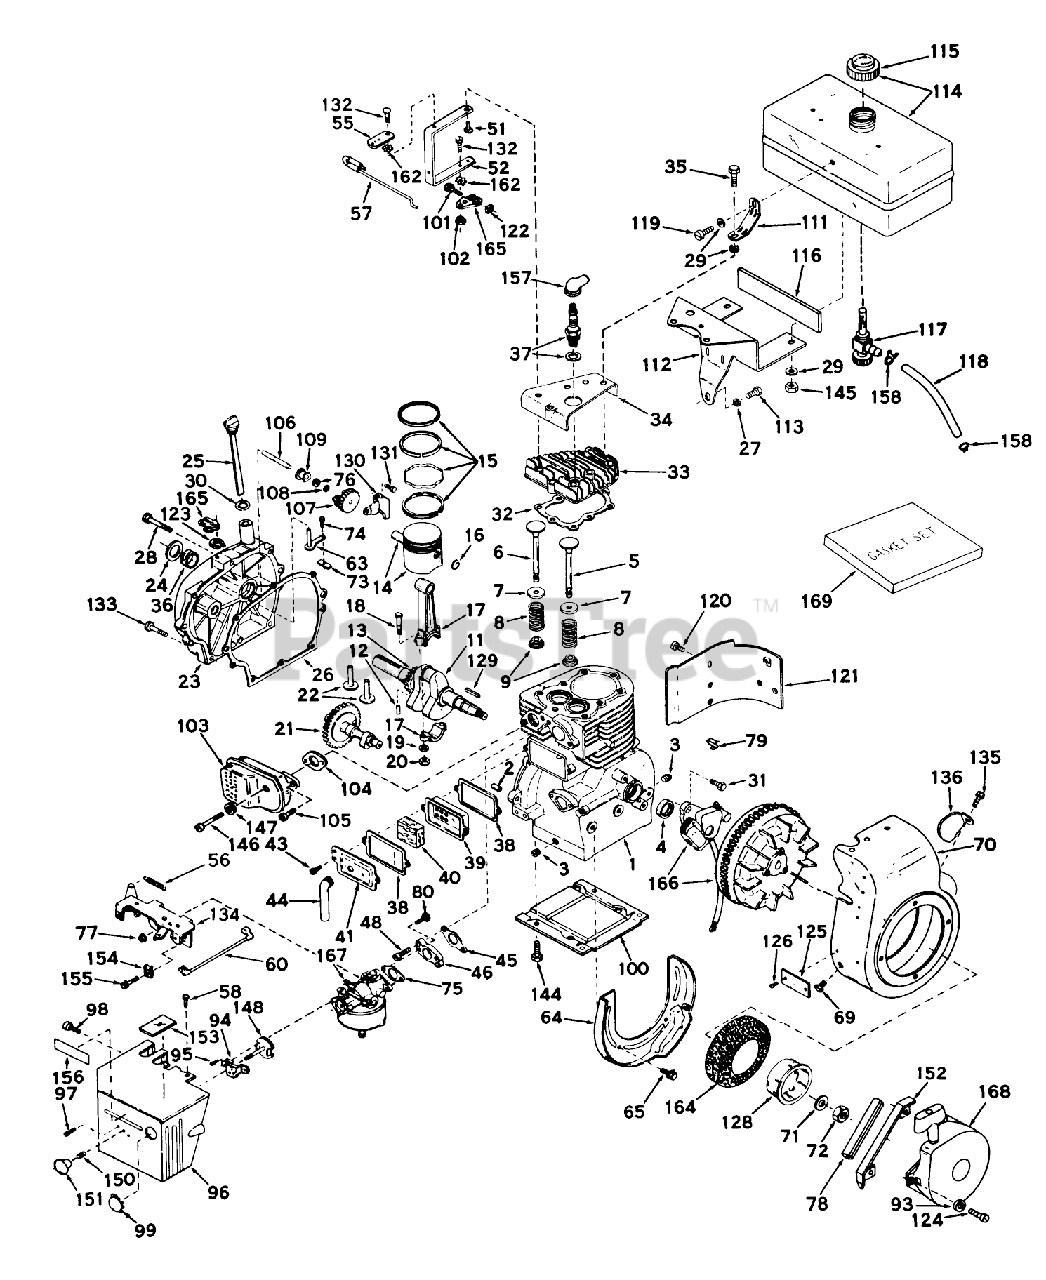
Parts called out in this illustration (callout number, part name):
1	Cylinder Assy. (Incl. Nos. 2, 3 4)
2	Pin-Dowel
3	Plug-Drain, Oil (SQH 1/4-18)
4	Seal, Oil
5	Valve, Intake (Std.)(Incl. No. 9)
5	Valve, Intake (1 /32" oversize)(Incl. No. 9)
6	Valve, Exhaust (Standard)(Incl. No. 9)
6	Valve, Exhaust (1/32" oversize)(Incl. No. 9)
7	Cap-Spring, Valve
8	Spring-Valve
9	Keeper-Spring, Valve
11	Crankshaft Assy. (Incl. Nos. 12 13)
12	Pin, Groove
13	Gear-Crankshaft
14	Piston Pin Assy., Std., (Incl. 2 of No. 16)
14	Piston Pin Assy., .010 oversize (Incl. 2 of No. 16)
14	Piston Pin Assy., .020 oversize (Incl. 2 of No. 16)
15	Ring Set (Standard)
15	Ring Set (.010 Oversize)
15	Ring Set (.020 Oversize)
17	Rod As sy. (Incl. Nos. 18, 19 20)
18	Bolt, Connecting Rod
19	Washer
21	Camshaft
22	Lifter Valve
23	Cover, Cylinder (Incl. Nos. 24 106)
24	Oil Seal
25	Dipstick, Oil (Incl. No. 30)
26	Gasket-Cover, Cylinder
27	Lockwasher
28	Screw (1/4-20 x 1-1/4)
29	Washer
30	Gasket
31	Screw
32	Gasket-Head, Cylinder
33	CYLINDER HEAD
34	Cover, Cylinder head
35	Screw Hex Hd. Cap
36	Bushing-Crankshaft
37	SPARK PLUG
38	Gasket-Breather
39	Body-Breather
40	Element-Breather
41	Cover-Valve
43	Screw
44	Tube-Breather
45	Gasket-Intake
46	Flange, Carburetor (Incl. Nos. 77 80)
48	Screw
51	Rivet, Split
52	Lever, Governor
56	Spring, Extension
57	Link, Governor to Throttle
58	Screw-Hex Washer Hd.
60	Wire, Ground
63	ROD ASSY, Governor
64	Baffle Blower Housing
65	Screw (1/4-20x19/32)
69	Screw, Hex Hd.
70	Housing, Blower
71	Washer
73	Yoke-Governor
74	Screw (6-40x5/16)
75	Gasket-Carburetor
76	Washer-Flat
77	Nut and Lock Washer (1/4-28)
78	Seal, Snowguard
79	51004 GIL ROTARY TI
80	Screw
93	Washer
94	Bracket-Choke
95	Screw (10-32 x 1/2)
96	Cover, Carburetor
97	752 SICKLE BAR MOWE
98	Screw, Pan Hd. Metal
99	Plug
100	Base Engine
101	Screw
102	Nut-Lock
103	Muffler
104	Gasket Exhaust
105	Screw
106	Shaft-Governor
107	Governor Gear ASM
108	Ring-Retaining
109	Spool-Governor
111	Brace, Fuel Tank
112	41057/58 ROTARY TIL
113	Screw
114	Tank Assy., Fuel (Incl. No. 115)
115	Cap, Fuel
116	Strip
117	Fitting Shut-off, Fuel
118	Line-Fuel
119	Screw
120	Screw
121	Emnsion, Blower Housing
122	Nut-Lock
123	Ring-Retaining
124	Screw
125	IDENTIFICATION PLATE
126	DRIVE STUD
128	Cup-Starter
129	Key, Flywheel
130	Bracket, Governor
131	Screw (10-32 x 35/64)
132	Screw
133	Screw
134	Bracket Assy., Speed Control (Incl. No. 56)
135	Screw
136	Screw
144	Screw
145	LOCKNUT
146	Screw Hex Hd. Cap
147	Washer
148	Plate, Choke
150	Spring, Compression
151	Knob, Choke
152	Guard, Starter
153	Decal, Operating
154	Conduit
155	Screw (10-32 x 3/8)
156	Decal, Choke
157	Cover-Spark Plug
158	Clamp-Line, Fuel
162	Washer-Lock
164	Screen, Air
165	Clamp-Lever, Governor
166	Magneto
167	Carburetor
168	Starter, Rewind
169	Gasket Set
